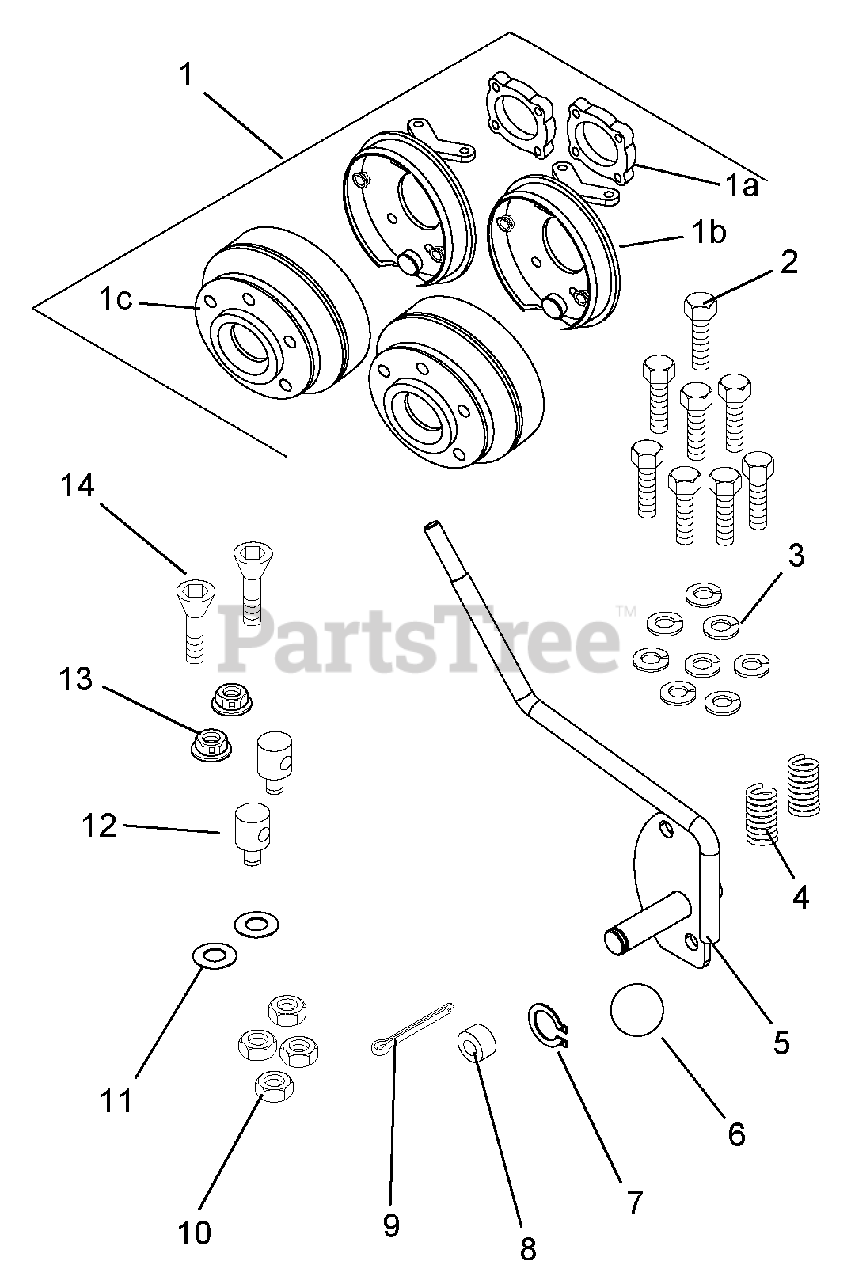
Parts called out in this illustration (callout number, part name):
1	Brake Assembly
2	Bolt, Hex 5/16-18 x 1-1/2 Grade 5 EP30
3	Washer, Lock 5/16 x 5/64
4	Spring, Compression
5	Lever, Brake Actuating
7	Ring, Retaining 5/8 x 3/64
8	Bushing, Sleeve
9	Pin, Cotter 1/10 x 3/4
10	Nut, Hex 3/8-16
11	Washer, Flat Steel 13/32 x 13/16
12	Pin, Pivot
13	Nut, Top Locking Flange 5/16-18
14	Screw, Machine 5/16-18 x 1-1/2 Flat Countersink
